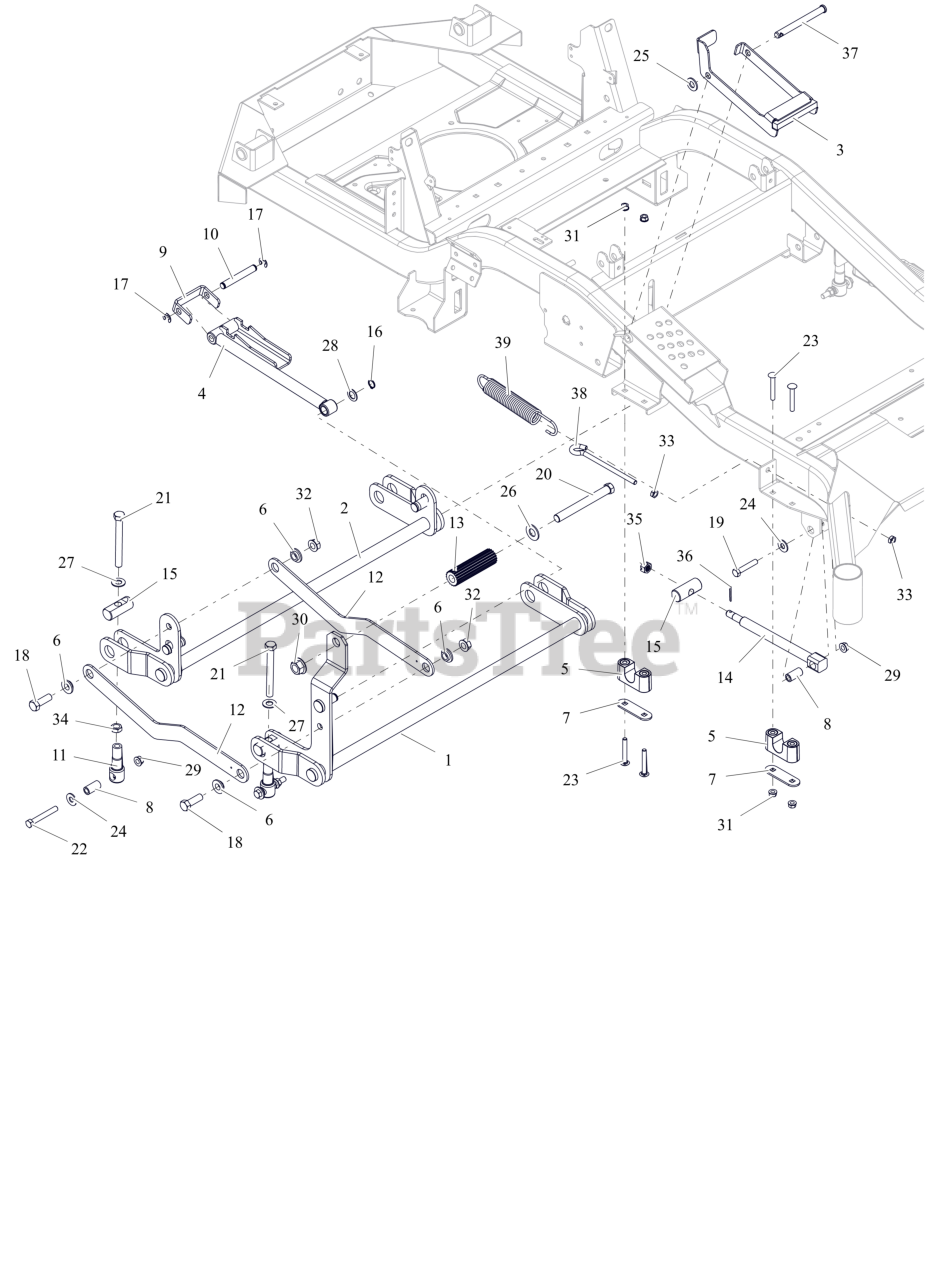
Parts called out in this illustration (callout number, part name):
1	WLDMT, FRONT DECK LIFT PIVOT
2	WLDMT, REAR DECK LIFT PIVOT
3	BRKT, HOC TRANSFER LOCK
4	WLDMT, HOC ARM
5	ASM-BUSHING, DECK LIFT
6	BSHG-FLG .515X.750X.395X1.120
7	PLATE, BEARING SUPPORT
8	SPACER, DECK LEVELING
9	BRKT, HOC LINE
10	ROD, HOC PIVOT
11	LINK, DECK LIFT FORMED
12	LINK, DECK LIFT
13	ROD, FOOT PEDAL (BLACK)
14	DRAG,LINK-HD
15	PIN, DECK LIFT
16	RG-RTNG-EXT .625X.050
17	RG-RTNG-EXT .500X.042 (E)
18	BLT,HEX .50-13X1.50 G5 ZCC
19	BLT,HEX .38-16X2.00 G5 ZCC
20	BLT, HEX .62-11X5.50 G5 FBP
21	BLT, HEX .50-13X4.50F G8 ZCC
22	BLT, HEX .38-16X2.75 G8 ZCC
23	BLT, RHSSN.31-18X2.25 G5 ZCC
24	WSHR,FLT .438X1.00X.083 ZCC
25	WSHR,FLT .531X1.062X.095 ZCC
26	WSHRFLT 5/8SAE CARBHARD FBP
27	WSHR, FLT .557X1.040X.102 ZCC
28	WSHR, FLT .630X1.005X.062 ZCC
29	NUT-LK-TOP-FLG .38-16 ZC120
30	NUT,FLG-TOP LK .625-11 FBP
31	NUT,LK-CTR-FLG .31-18 GF ZCC
32	NUT-LK-TOP-FLG .500-13 GF ZCC
33	NUT-JAM .375-16 G2 ZCC
34	NUT-JAM .500-13 G2 ZCC
35	NUT-SL .50-13
36	PIN,CTR.12X1.25EXTPRSQCT ZC120
37	PIN-SLIC .50X4.97X4.55 -ZCC
38	BOLT,.38-16 X 5.25-.62 DIA EYE
39	SG-TENS .162X1.25X8.25 WLD 25
